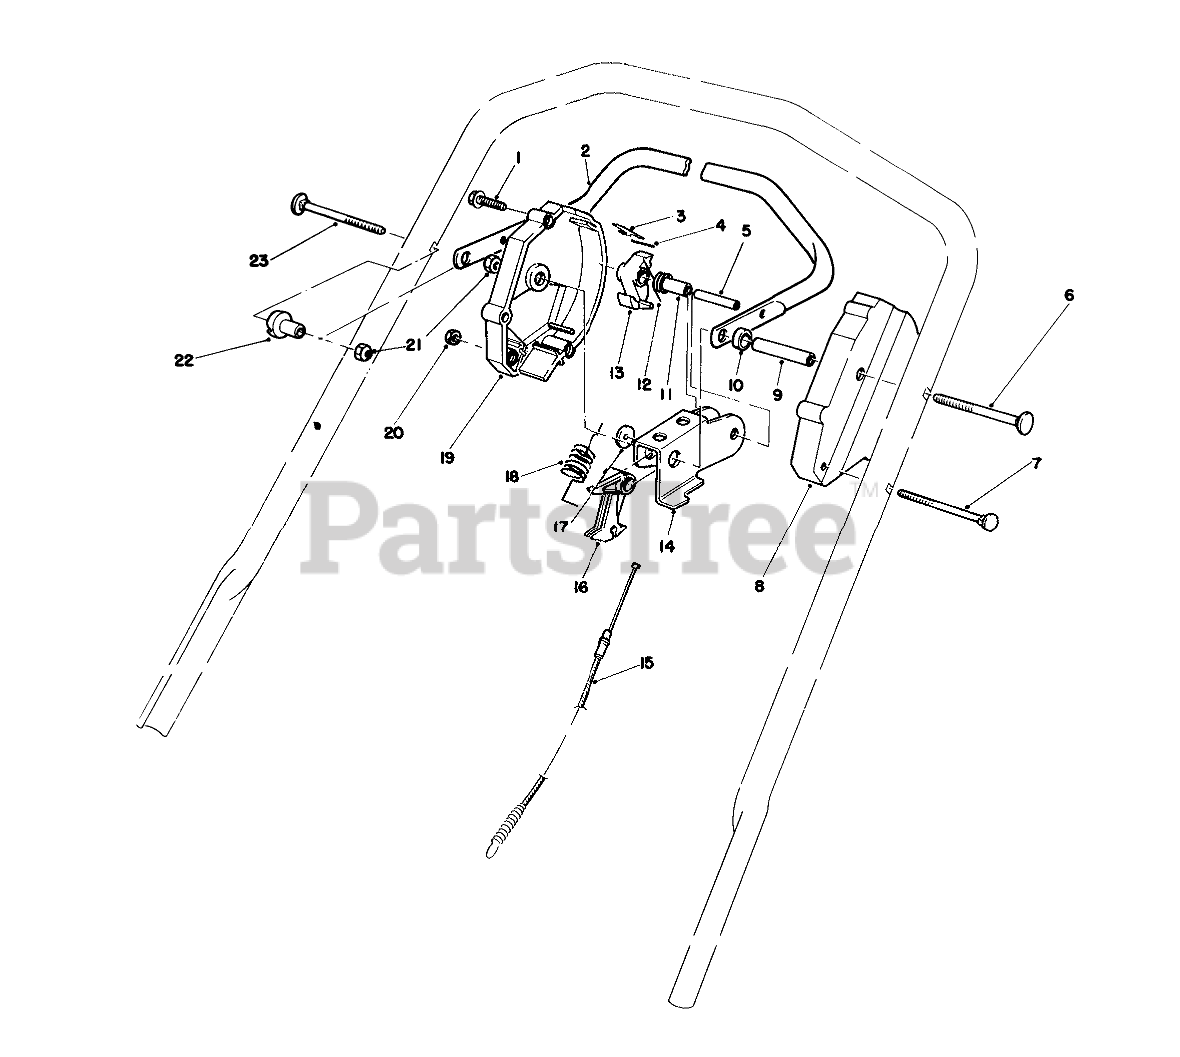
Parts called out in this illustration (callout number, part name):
1	SCREW-HWHTF
2	Bar-Control
3	SPRING-LEAF
4	PIN-INSERT
5	PIN-ROLL, SLOTTED
6	5/16-18 X 3 HNDLE SCREW
7	HANDLE SCREW
8	HOUSING-CONTROL, LH
9	TUBING-SPACER
10	SPACER-NYLON
11	SPACER
12	SPRING-TORSION
13	HOOK-CONTROL
14	ROCKER
15	Cable-Clutch
16	LEVER-CABLE
17	PLASTIC WASHER
18	Spring-Detent
19	Housing-Control R.H. (Incl. Ref. #3 & 4)
20	NUT-LOCK, NI
21	NUT-LOCK, NI
22	SPACER-SUPPORT
23	5/16-18 X 2 HNDLE SCREW
